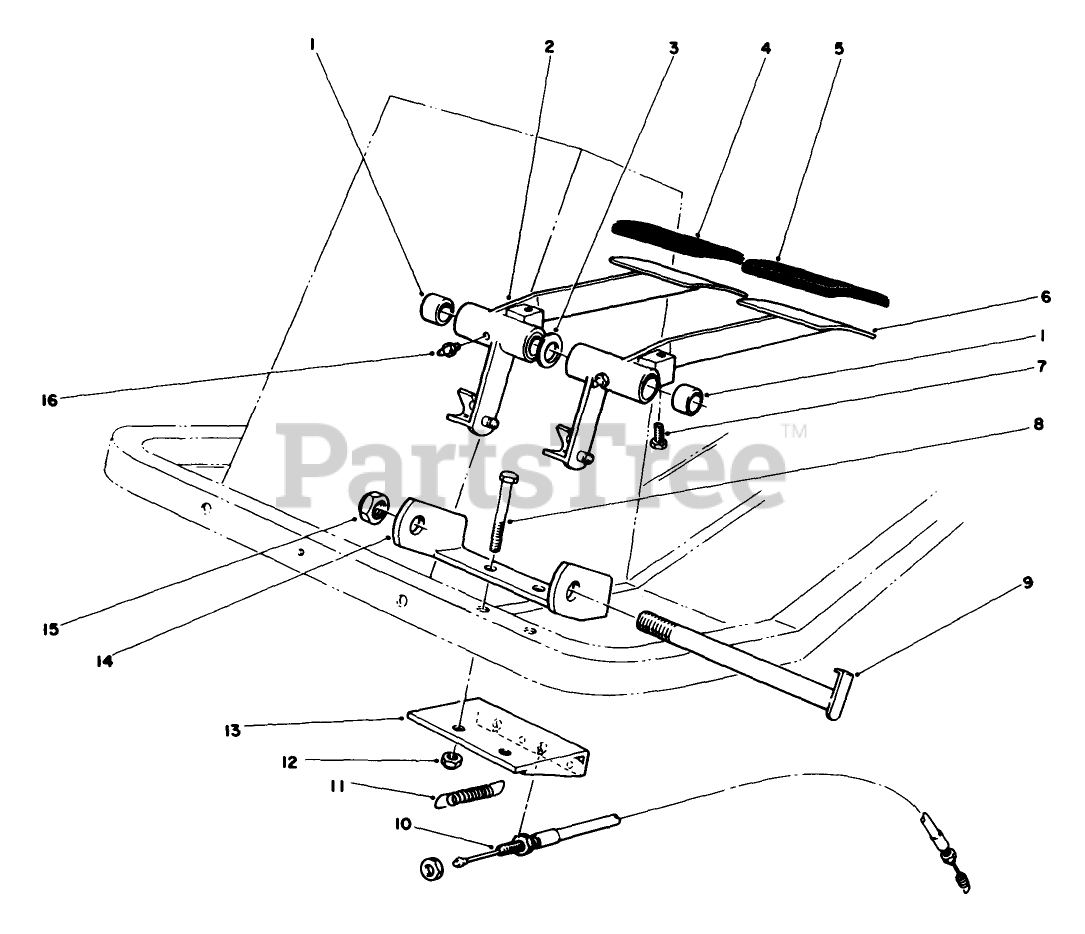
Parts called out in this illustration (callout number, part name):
1	BUSHING
2	Brake Pedal Assembly-R.H. (Incl. Ref. #1 & 16)
3	WASHER-FLAT
4	PAD-TURN, RIGHT
5	PAD-TURN, LEFT
6	Brake Pedal Assembly-L.H. (Incl. Ref. #1 & 16)
7	BOLT 60183
8	SCREW-HH
9	BRAKE PIN WA RO
10	BRAKE CABLE ASM
11	EXTENSION SPRING O
12	NUT-LOCK, NI
13	CABLE BRKT WA R
14	BRAKE PEDAL BRKT B
15	NUT-LOCK, NI
16	FITTING-GREASE
